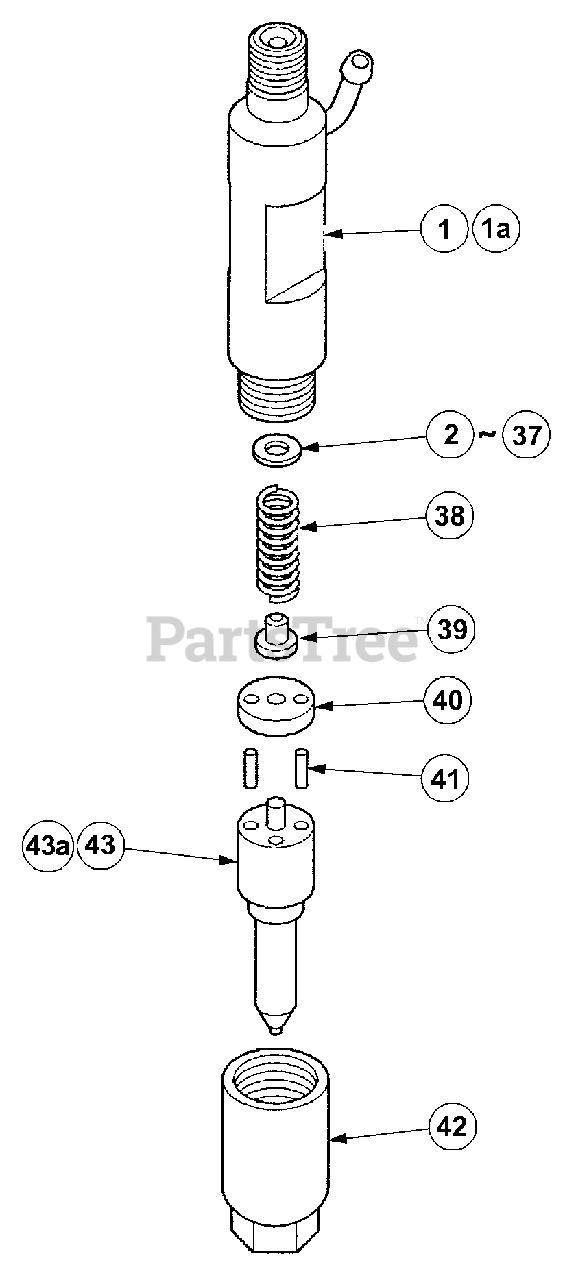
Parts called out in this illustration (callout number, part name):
1	Body Sub Ass'y.
1A	Body Sub Ass'y.
2	Washer, t=1.000
3	Washer, t=1.050
4	Washer, t=1.100
5	Washer, t=1.150
6	Washer, t=1.200
7	Washer, t=1.250
8	Washer, t=1.300
9	Washer, t=1.350
10	Washer, t=1.400
11	Washer, t=1.450
12	Washer, t=1.500
13	Washer, t=1.550
14	Washer, t=1.600
15	Washer, t=1.650
16	Washer, t=1.700
17	Washer, t=1.750
18	Washer, t=1.800
19	Washer, t=1.850
20	Washer, t=1.900
21	Washer, t=1.950
22	Washer, t=2.000
23	Washer, t=2.050
24	Washer, t=2.100
25	Washer, t=2.150
26	Washer, t=1.275
27	Washer, t=1.325
28	Washer, t=1.375
29	Washer, t=1.425
30	Washer, t=1.475
31	Washer, t=1.525
32	Washer, t=1.575
33	Washer, t=1.625
34	Washer, t=1.675
35	Washer, t=1.725
36	Washer, t=1.775
37	Washer, t=0.950
38	Spring, Pressure
39	Pin, Pressure
41	Pin, Straight
42	Nut, Nozzle Retaining
43	Nozzle Ass'y.
43A	Nozzle Ass'y.
